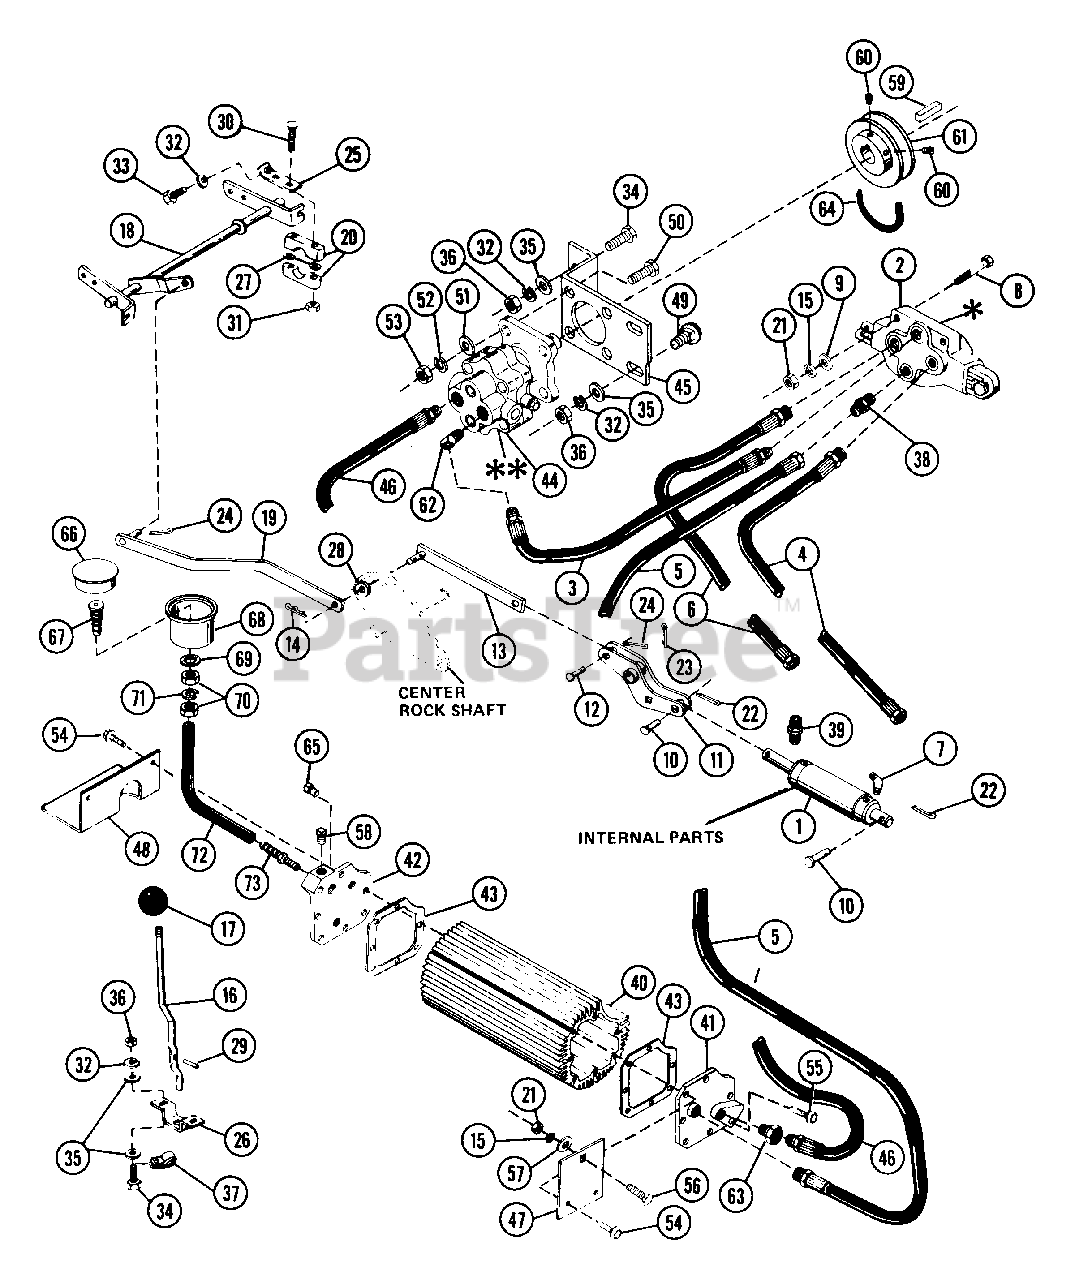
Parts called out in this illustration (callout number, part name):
1	CYLINDER ASSEMBLY
2	CONTROL VALVE
3	HYDRAULIC HOSE
4	HYDRAULIC HOSE
5	HYDRAULIC HOSE
6	HYDRAULIC HOSE
7	ADAPTER 9/16 TO 1/4
8	BLT-HEX .25-20X1.50 PL GR5
9	WSHR-FL-STL.281X.62X.065 PL
10	PIN-CLEV .494X1.94 YWZC
11	BELLCRANK
12	RVT-BTN .62X1.50 SPL
14	PIN-HAIR INT .09X.188 PL
15	WSHR-LK .250X.077 HVY PL
16	CONTROL ROD
17	KNOB-STEERING LOCK
18	FRONT ROCK SHAFT SERVICE ASSEM
19	FRONT ROCK SHAFT CONNECTOR LIN
21	NUT-HEX .250-20 PL
22	PIN-COTR .12X1.0 PL
23	PIN-COTR .18X1.25 PL
24	PIN-COTR .18X1.0 PL
26	BRACKET
27	WSHR-FL-STL .406X.750X.005
28	WSHR-FL-STL.812X1.500X.139
29	PIN-GRV .250X.75 TP B PL
30	BLT-RDHDSQNK .38-16X2.25 SHTPL
31	NUT-LK-CTR .375-16 GR A PL
32	WSHR-LK .312X.097 PL HVY
33	BLT-HEX .31-18X1.25 PL GR5
34	BLT-HEX .31-18X.75 PL GR2
35	WSHR-FL-STL .38X.875X.083 PL
36	NUT-HEX .312-18
37	J-CLAMP
38	CONNECTOR
39	ADAPTER
40	OIL RESERVOIR
41	CIRCULATION COVER
42	FILLER COVER
44	PUMP HYDRAULIC
45	PUMP BRACKET
46	HYDRAULIC HOSE
47	BRACKET
48	MOUNTING BRACKET
49	BLT-RDHDSQNK .31-18X.75 GR5 PL
50	BLT-HEX .38-16X1.00 PL
51	WSHR-FL-STL .380X.626X.033
52	WSHR-LK .375X.094 MED PL
53	NUT-HEX .375-16
54	SCR-TAP 10-24X.75 HWH PL TR
55	SCR-TAP 10-24X1.75 HWH PL TR
56	BLT-RDHDSQNK .25-20X.75
57	WSHR-FL-STL.312X.734X.065PL
58	PIPE PLUG
58	PIPE PLUG ASSEMBLY
59	KEY-SQ .125X1.00X.125 SAE 1035
60	SCR-SET .25-20X.38 SKHCUP OH
62	ADAPTER 3/8 TO 9/16
63	ADAPTER 9/16 TO 3/8
64	V-BELT, 3L-RAW EDGE
65	PIPE PLUG
66	PLASTIC COVER
67	FITTING
68	OIL EXPANSION CUP
69	FIBER WASHER
70	NUT .625-32 ALUM
71	WSHR-LK-INT .625X.045 PL
72	HOSE
73	CONNECTOR
